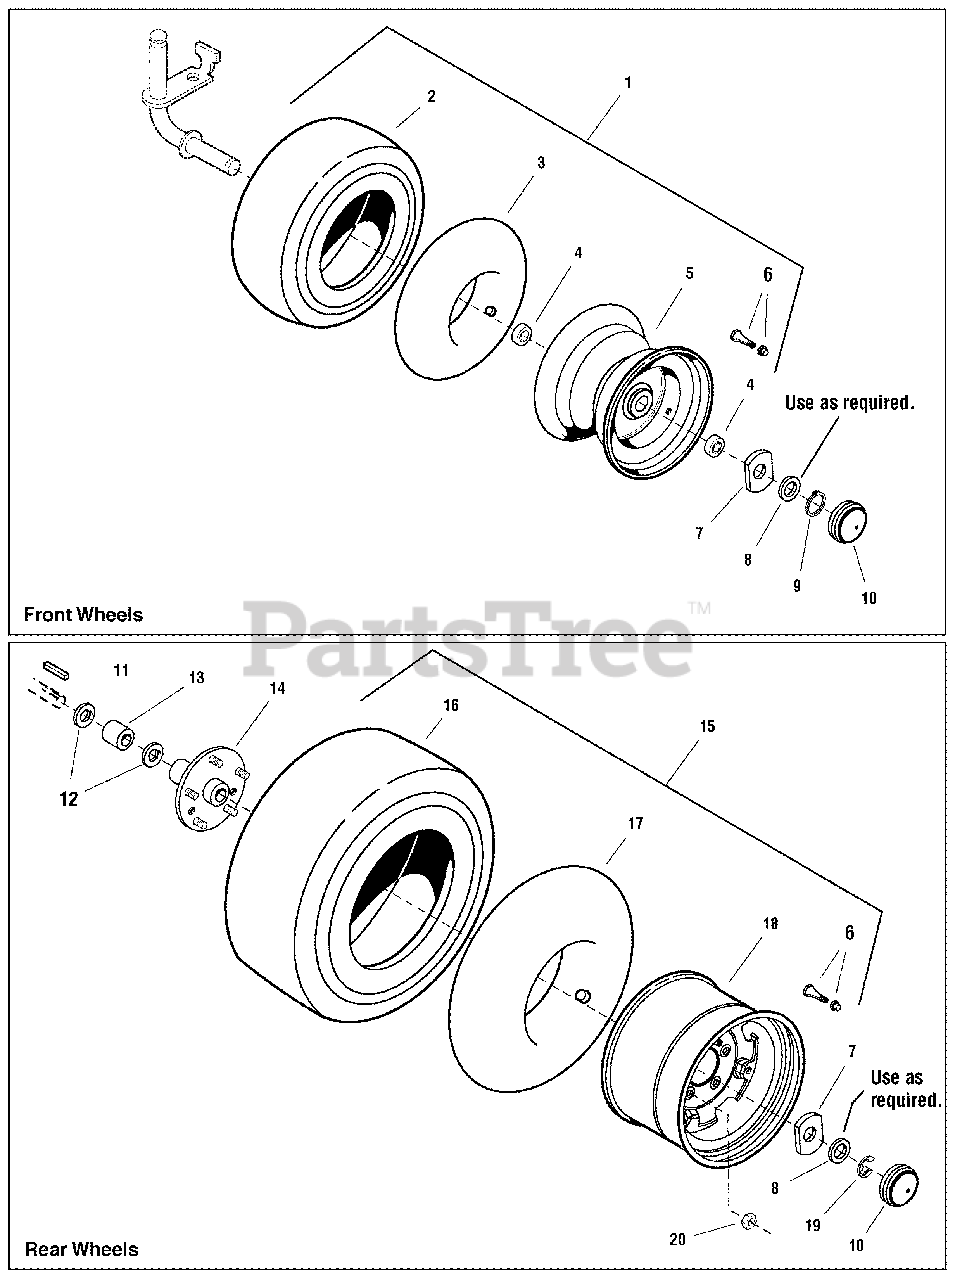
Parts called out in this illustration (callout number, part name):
1	WHEEL & TIRE ASSEMBLY, Front, (Includes Ref. Nos. 2, 3, 4, 5 & 6)
2	TIRE, 16 x 6-1/2 - 8 Super Turf, Front
3	TUBE, Tire 16 x 6-1/2 - 8, Front
4	WHEEL, w/Bearings, 5 3/8 x 7-15/16, Front
5	VALVE STEM & CAP ASSEMBLY
6	WASHER, Special, Hub Cap, 1 x 2-1/2
7	WASHER, 1"
8	RING, Retainer
9	CAP, Hub Grey, 2-23/64
10	KEY, HI PRO, 1/4 x 2
12	SPACER, 1-1/16 x 1-1/2 x 1-23/32, Black
13	PLATE & HUB ASSEMBLY, Rear Wheel w/Studs
14	WHEEL & TIRE ASSEMBLY, Rear 23" (Includes Ref. Nos. 6, 16, 17 & 18)
15	TIRE, 23 x 10-1/2 - 12 Super Turf, Rear
16	TUBE, Tire 23 x 10-1/2 - 12, Rear
17	WHEEL, 7 x 12, Rear
18	RING, Shaft
19	NUT, Hex 7/16-20, For Wheel Bolt
